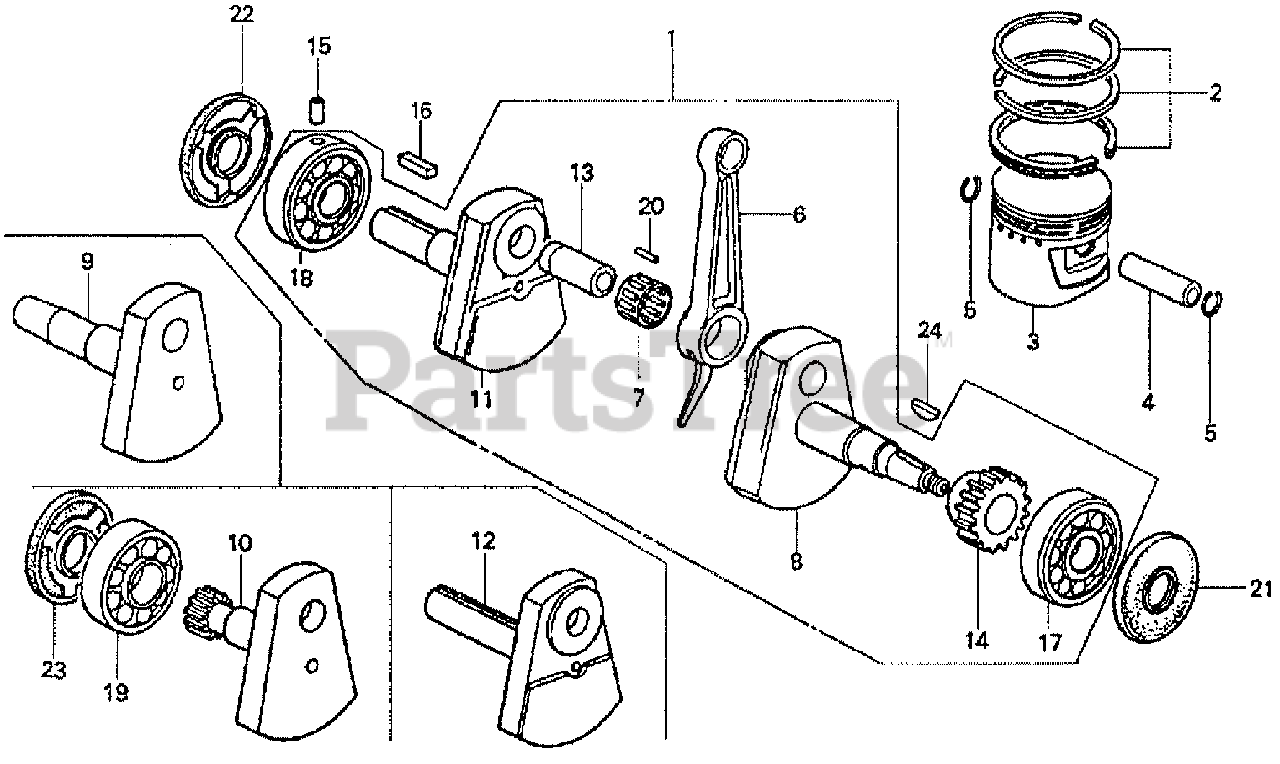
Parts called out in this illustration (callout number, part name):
1	CRANKSHAFT
2	RING SET, PISTON (STD) (NOT AVAILABLE)
2	RING SET, PISTON (OS 0.25)
2	RING SET, PISTON (OS 0.50)
2	RING SET, PISTON (0.75)
3	PISTON (STD) (NOT AVAILABLE)
3	PISTON (OS 0.25)
3	PISTON (OS 0.50)
3	PISTON (0.75)
4	PIN, PISTON
5	CLIP, PISTON PIN (19MM)
6	ROD, CONNECTING
7	RETAINER, ROLLER
8	CRANKSHAFT, R.
12	CRANKSHAFT, L.
13	PIN, CRANK (N/A: SEE ASSEMBLY)
14	GEAR, TIMING
15	PIN, KNOCK (7X12) (NOT AVAILABLE)
17	BEARING, RADIAL BALL (6306S)
18	BEARING, SPECIAL BALL (6306S6HS) (NOT AVAILABLE)
20	ROLLER, ROD (3X16)
21	OIL SEAL (30759) (NOT AVAILABLE)
22	OIL SEAL (PJ30779)
24	KEY, SPECIAL WOODRUFF (25X18)
